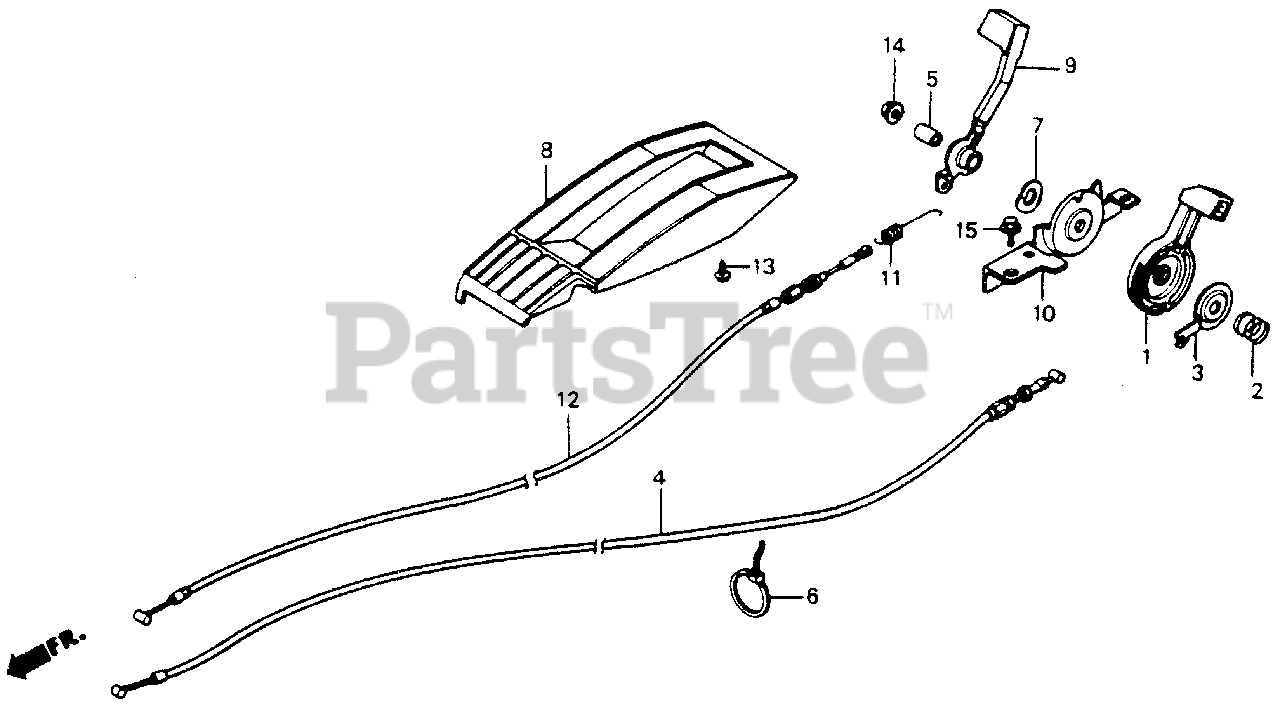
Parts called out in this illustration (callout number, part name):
1	LEVER, THROTTLE
2	SPRING, THROTTLE LEVER
3	SEAT, SPRING
4	CABLE, THROTTLE
5	COLLAR, RECOIL STARTER
6	TIE, CABLE
7	WASHER, WAVE (11MM)
8	COVER, CONTROL
9	LEVER, CHANGE
10	PLATE, STOPPER
11	SPRING, CHANGE TENSION
12	CABLE, CHANGE
13	SCREW, TAPPING (5X12)
14	NUT, FLANGE (6MM)
15	BOLT, FLANGE (6X10)
